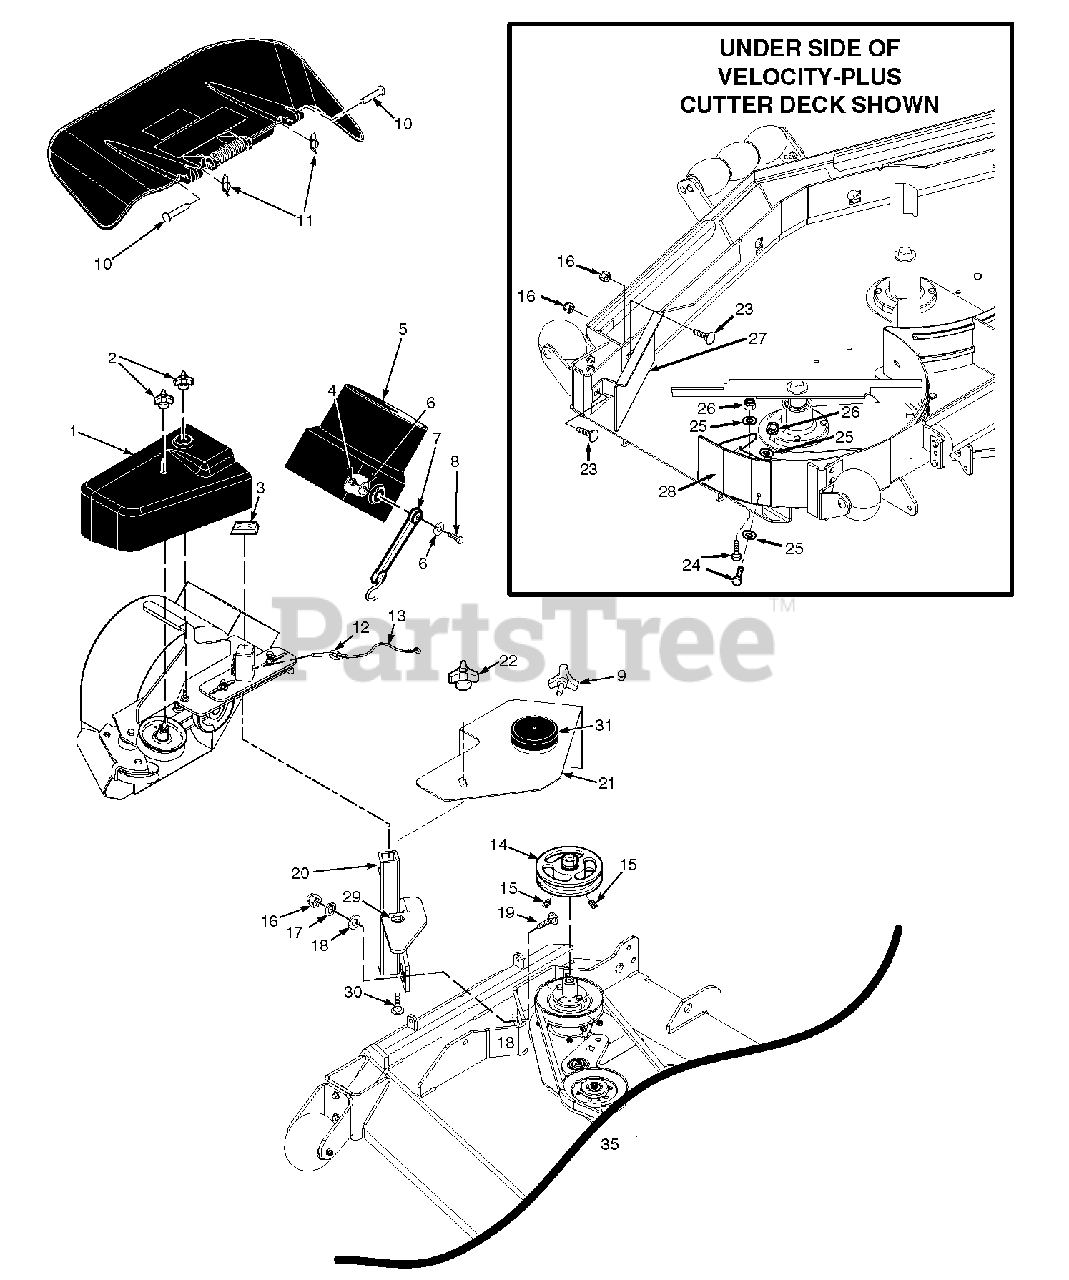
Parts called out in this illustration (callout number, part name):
1	Belt Cover, 48"
1	Belt Cover, 52"
2	Wingnut, Plastic 3/8" Small
3	Cap, Square Vinyl
4	Nut, Elastic Stop 1/4-20
5	Adapter, Blower GC-STC,
6	Flatwasher, 1/4-.312 x .750 x .065
7	Rubber Strap 7-3/4"
8	Bolt, Hex Head 1/4-20 x 1-1/4"
9	Knob W/Stud, 3/8-16 x 1-1/4"
10	Clevis Pin, 5/16 x 1-1/2"
11	Pin, Rue Cotter 5/16 Dia.
12	Pin, Ring 1/2 x 2-1/4"
13	Lanyard
14	Pulley, 4.0" Dia. 1.125 Bore
15	Setscrew, 5/16-18 x 3/8"
16	Nut, Elastic Stop 3/8-16
17	Lockwasher, 3/8"
18	Flatwasher, 3/8-.391 x .938 x .105
19	Bolt, Carr. 3/8-16 x 1-1/4"
20	Mounting Post Weldment, Blower
21	Belt Cover Assembly, w/Cap - 48"
21	Belt Cover Assembly, w/Cap - 52"
22	Wing Nut, 3/8 Plastic - Small
23	Bolt, Carriage 3/8-16 x 1"
24	Bolt, Hex Head 5/16-18 x 1"
25	Flatwasher, 5/16-.375 x .875 x .083
26	Nut, Elastic Stop 5/16-18
27	Baffle Weldment 48 / 52
28	Baffle, Turbo 48" Deck
28	Baffle, Turbo 52" Deck
29	Nut, Push-On 3/8 Thread
30	Bolt, Carriage 3/8-16 x 1-1/4"
31	Cap, Spindle
